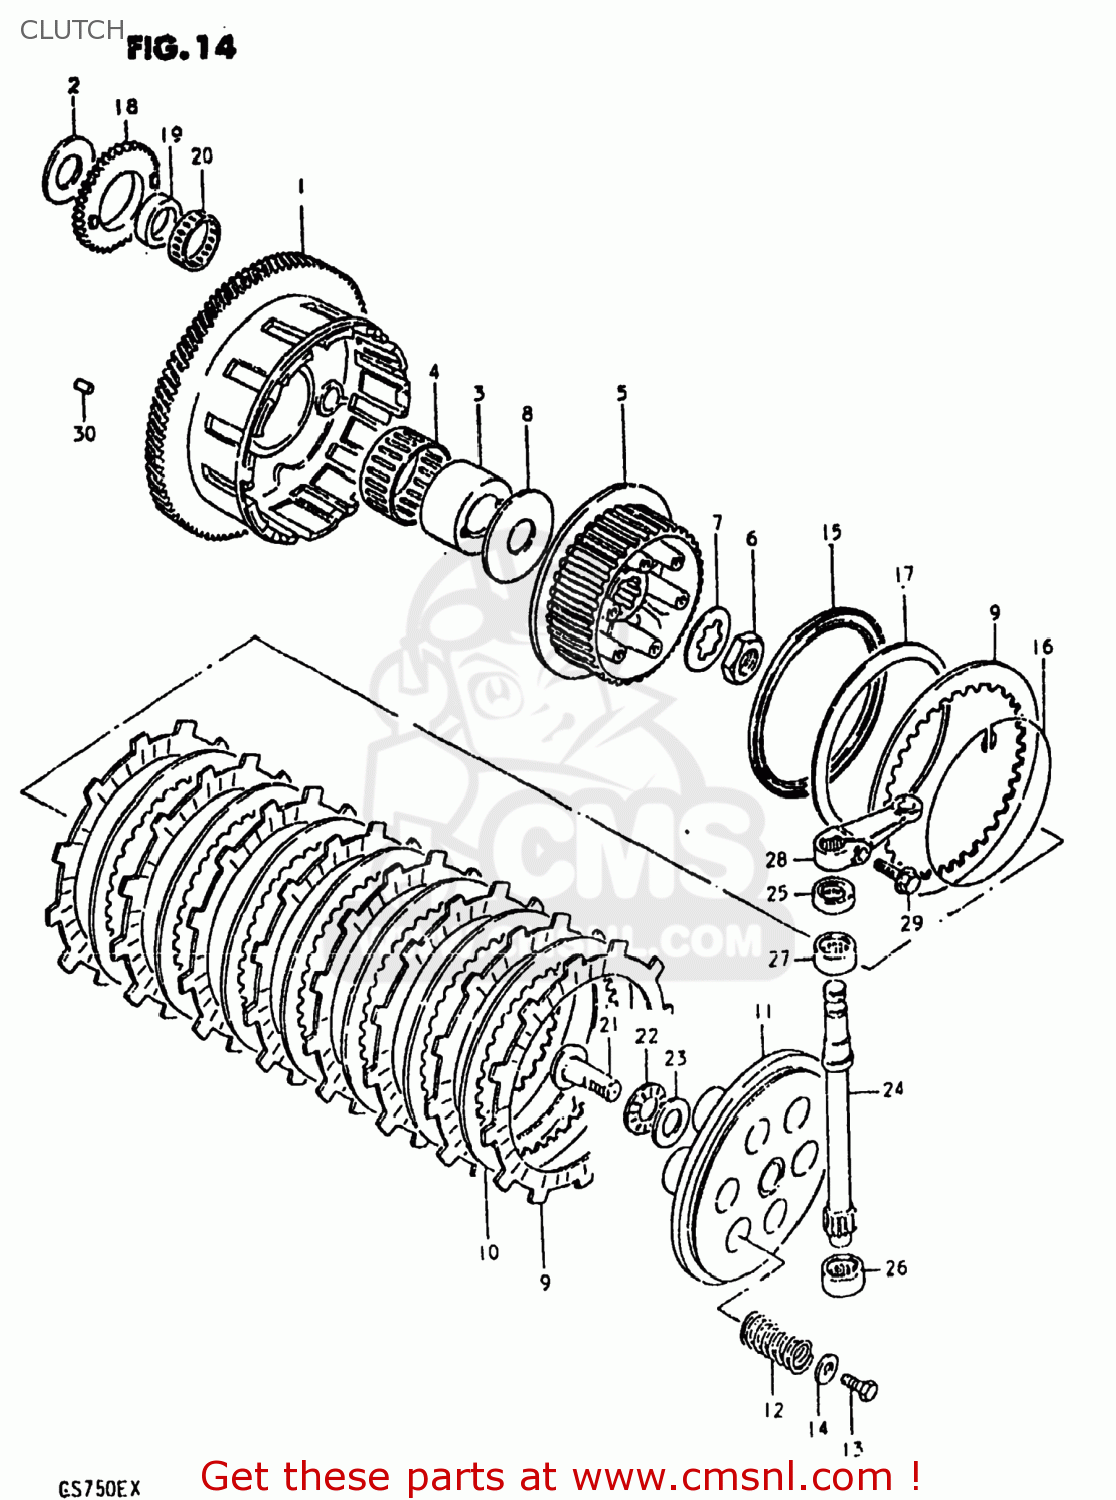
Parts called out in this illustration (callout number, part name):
1	GEAR ASSEMBLY,PRIMARY DRIVE
2	WASHER
3	SPACER,PRIMARY DRIVEN
4	BEARING
5	HUB,CLUTCH SLEEVE
6	NUT
7	WASHER,LOCK
8	WASHER(25X66X3.5)
9	PLATE,CLUTCH DRIVE (MCA)
10	PLATE,CLUTCH DRIVEN(T:2.0) (NAS)
11	DISC,CLUTCH PRESSURE
12	SPRING
13	BOLT, UPPER
14	WASHER
15	SEAT,WAVE WASHER
16	RING,STOPPER
17	WASHER
18	GEAR,ENG OIL PUMP DRIVE(NT:38)
19	SPACER,OIL PUMP DRIVE GEAR
20	BEARING(36X40X10)
21	RACK,CLUTCH RELEASE
22	BEARING(15X28X2)
23	WASHER
24	PINION,CLUTCH RELEASE
25	OIL SEAL
26	BEARING(12X19X12)
27	BEARING(15X22X12)
28	ARM,CLUTCH RELEASE
29	BOLT,REAR
30	CUSHION,PRIMARY DRIVEN GEAR
